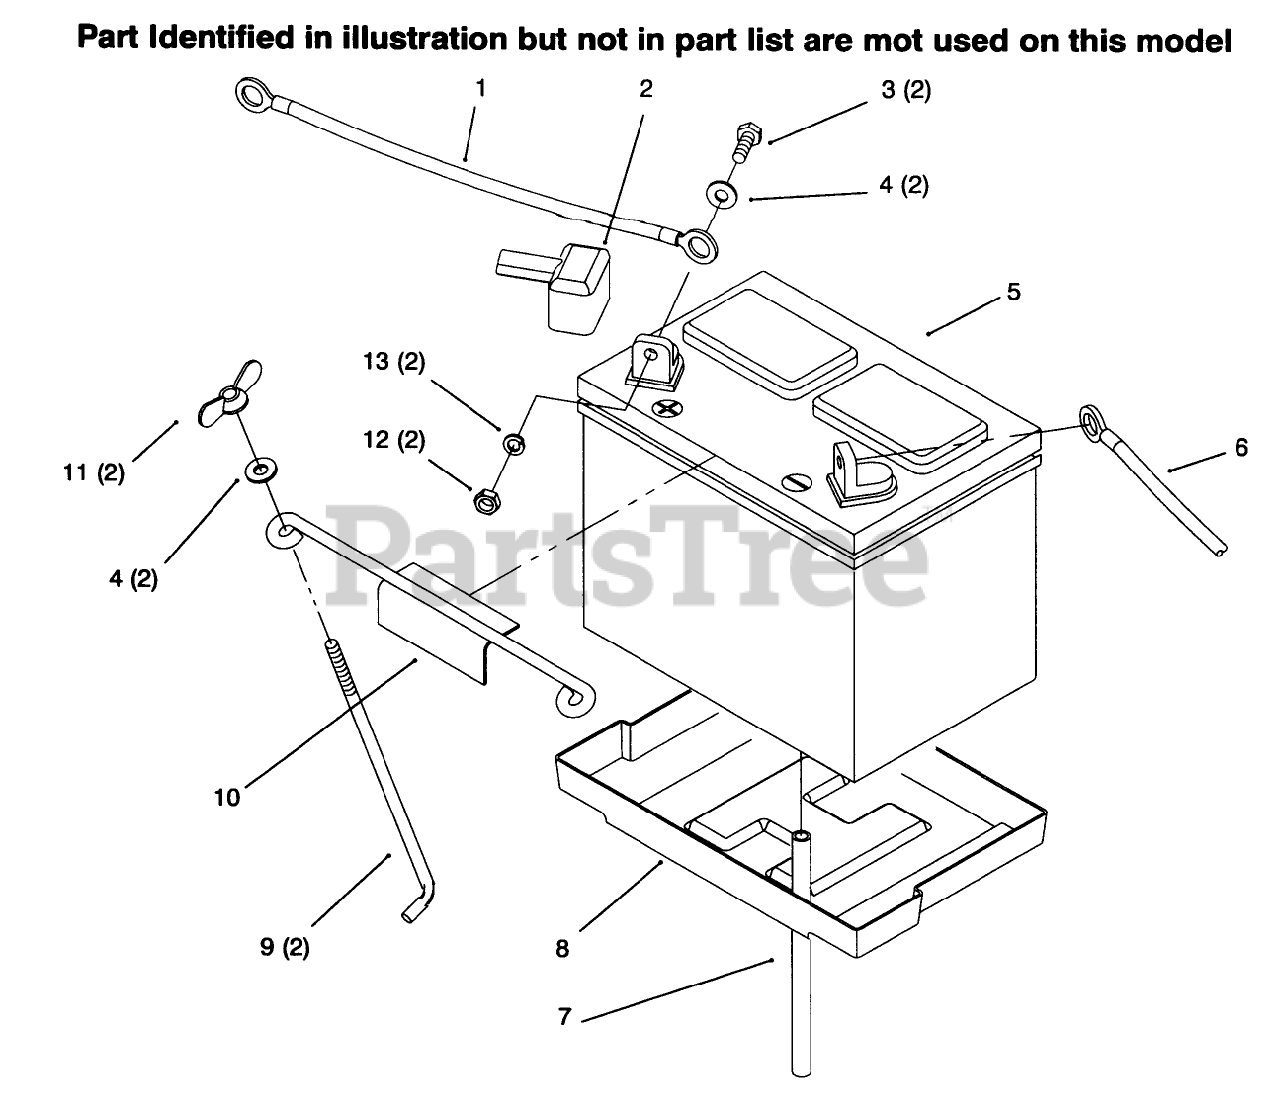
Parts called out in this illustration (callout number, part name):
1	CABLE-BLACK
3	SCREW-HH
4	WASHER-FLAT
7	TUBE-21" BATTERY DRAIN
8	TRAY-BATTERY
9	HOOK-BATTERY RETAIN
10	HOLDDOWN-BATTERY
11	NUT-WING
12	NUT-LOCK, NI
13	WASHER-LOCK
